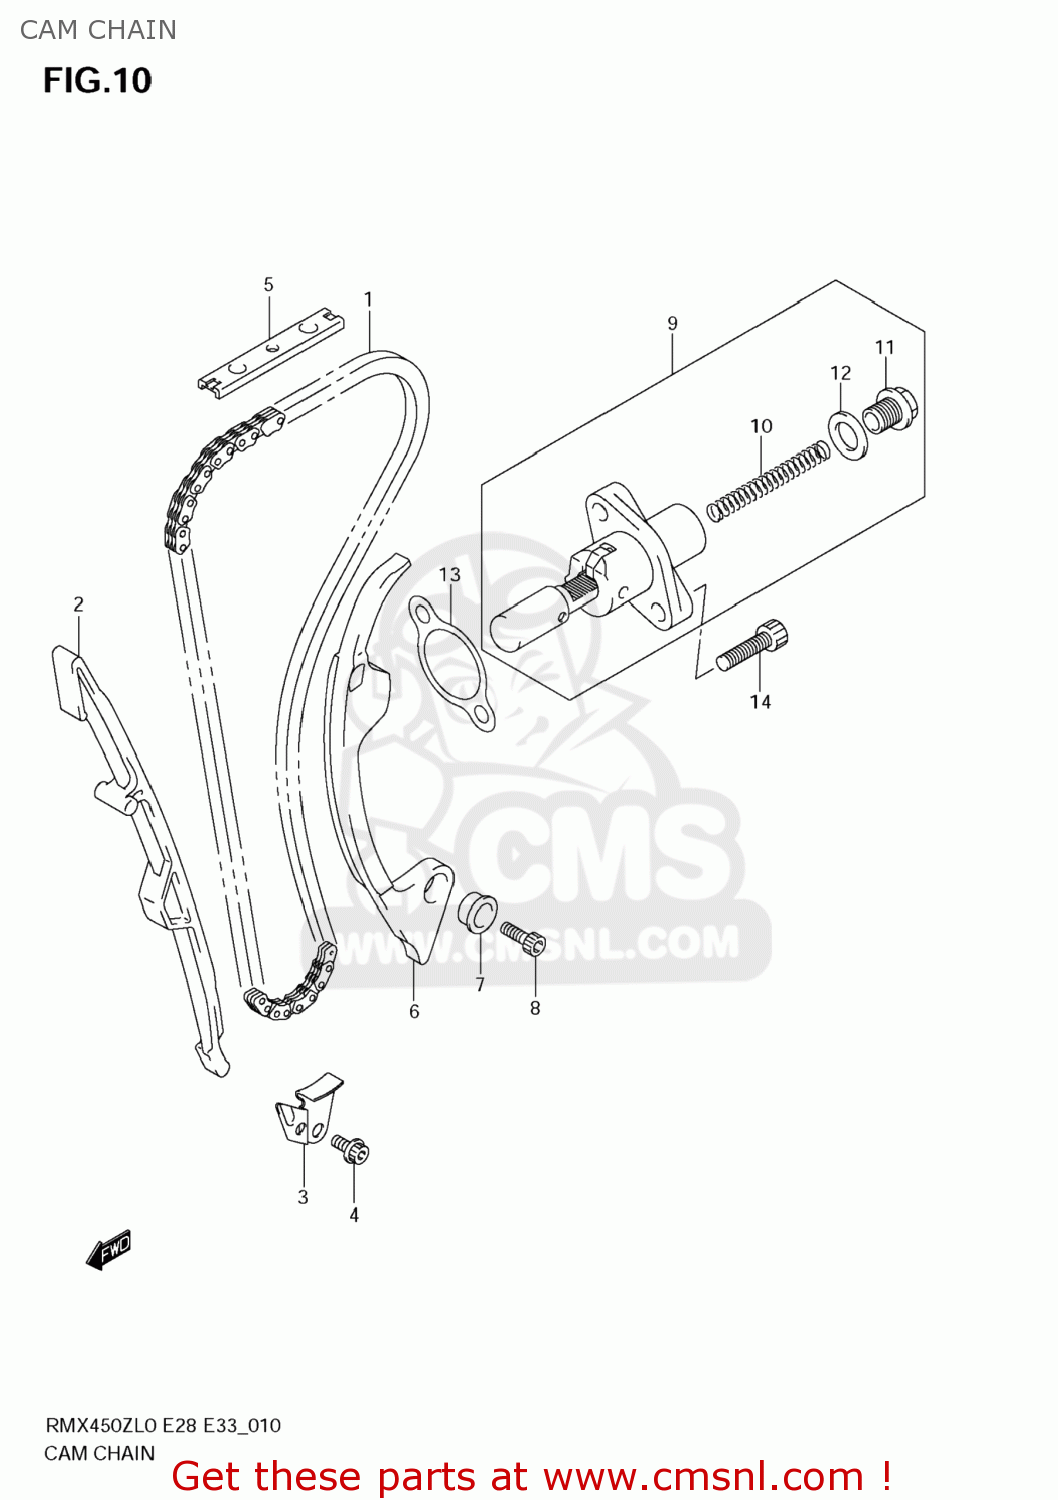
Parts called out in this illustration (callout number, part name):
1	CHAIN,CAMSHAFT DRIVE
2	GUIDE,CAM CHAIN NO.1
3	RETAINER,CAM CHAIN GUIDE NO.1
4	BOLT
5	GUIDE,CAM CHAIN NO.2
6	TENSIONER,CAM CHAIN
7	SPACER,CAM CHAIN TENSIONER
8	BOLT
9	ADJUSTER ASSY,TENSIONER
10	SPRING
11	PLUG,FR TENSIONER ADJ
12	GASKET,TENSIONER ADJUSTER (NAS)
13	GASKET,TENSIONER ADJUSTER (NAS)
14	BOLT
